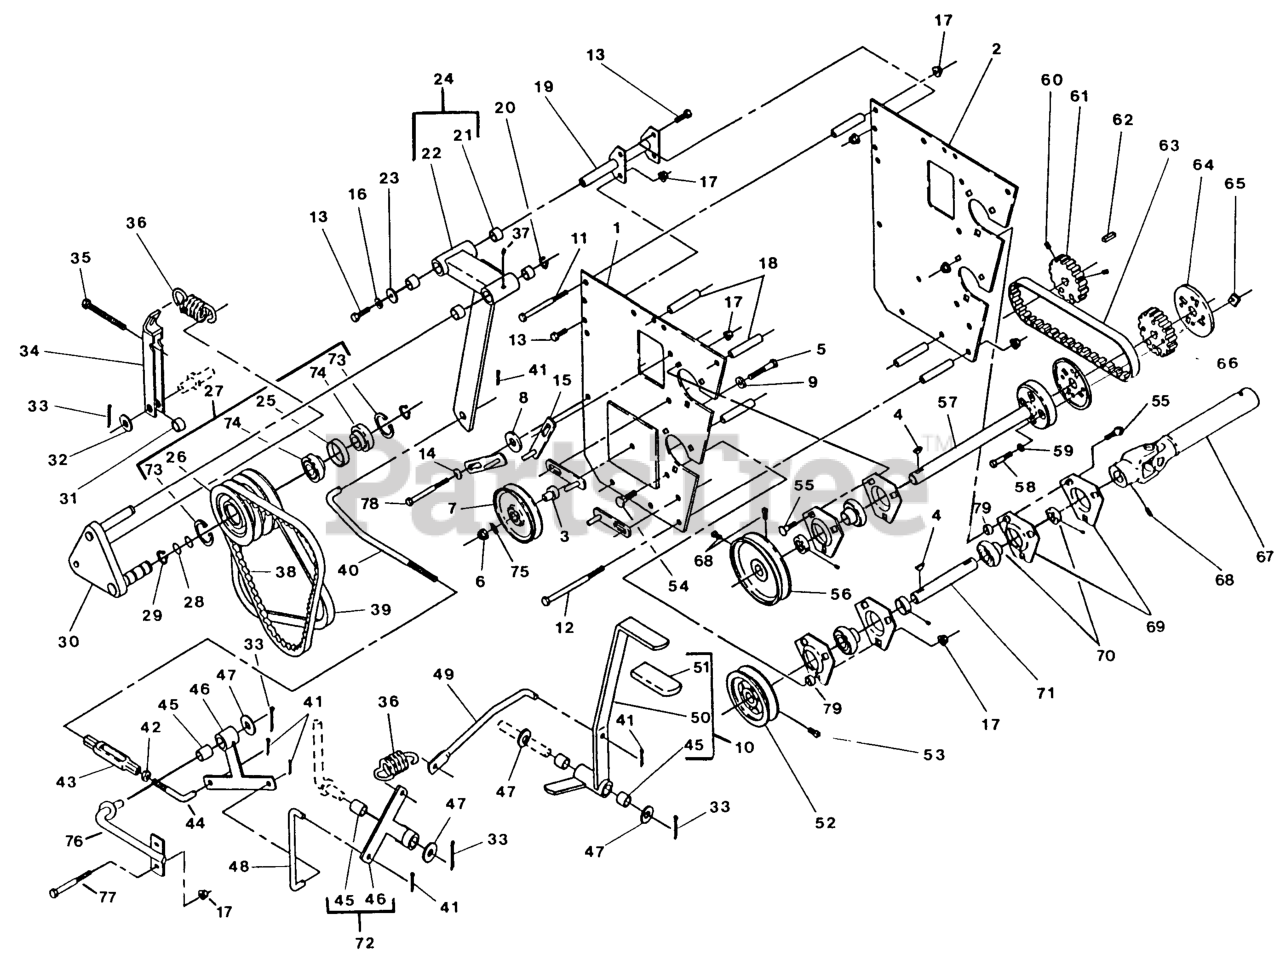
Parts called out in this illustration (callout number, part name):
2	PANEL,POWER TRAIN PNTD
4	KEY-WOODRUFF
12	SCREW-HH
14	WASHER-SPRING
15	GUIDE-BELT
16	WASHER-LOCK
22	Control Wldm't - Tmfr. Sheave
24	CNTRL ASSY,TRANS SHV
25	SPACER,TRANSFER BEARING
28	O-RING,
36	SPRING,BELT TENSION
38	BELT,PRIMARY DRIVE
39	BELT,SECONDARY DRIVE
40	ROD,PTO LOW RH THD
44	ROD,PTO RH LOW LH THD
45	SLEEVE-BEARING
49	ROD,PTO UPPER
51	GRIP-LEVER
52	SHEAVE,5.5 B
53	SCREW-SET
59	WASHER-LOCK
63	BELT,DRIVE POSITIVE
69	HOUSING-FLANGE
70	BEARING,W/COLLAR
74	BEARING
76	WLD,BELLCRANK SUPPORT
